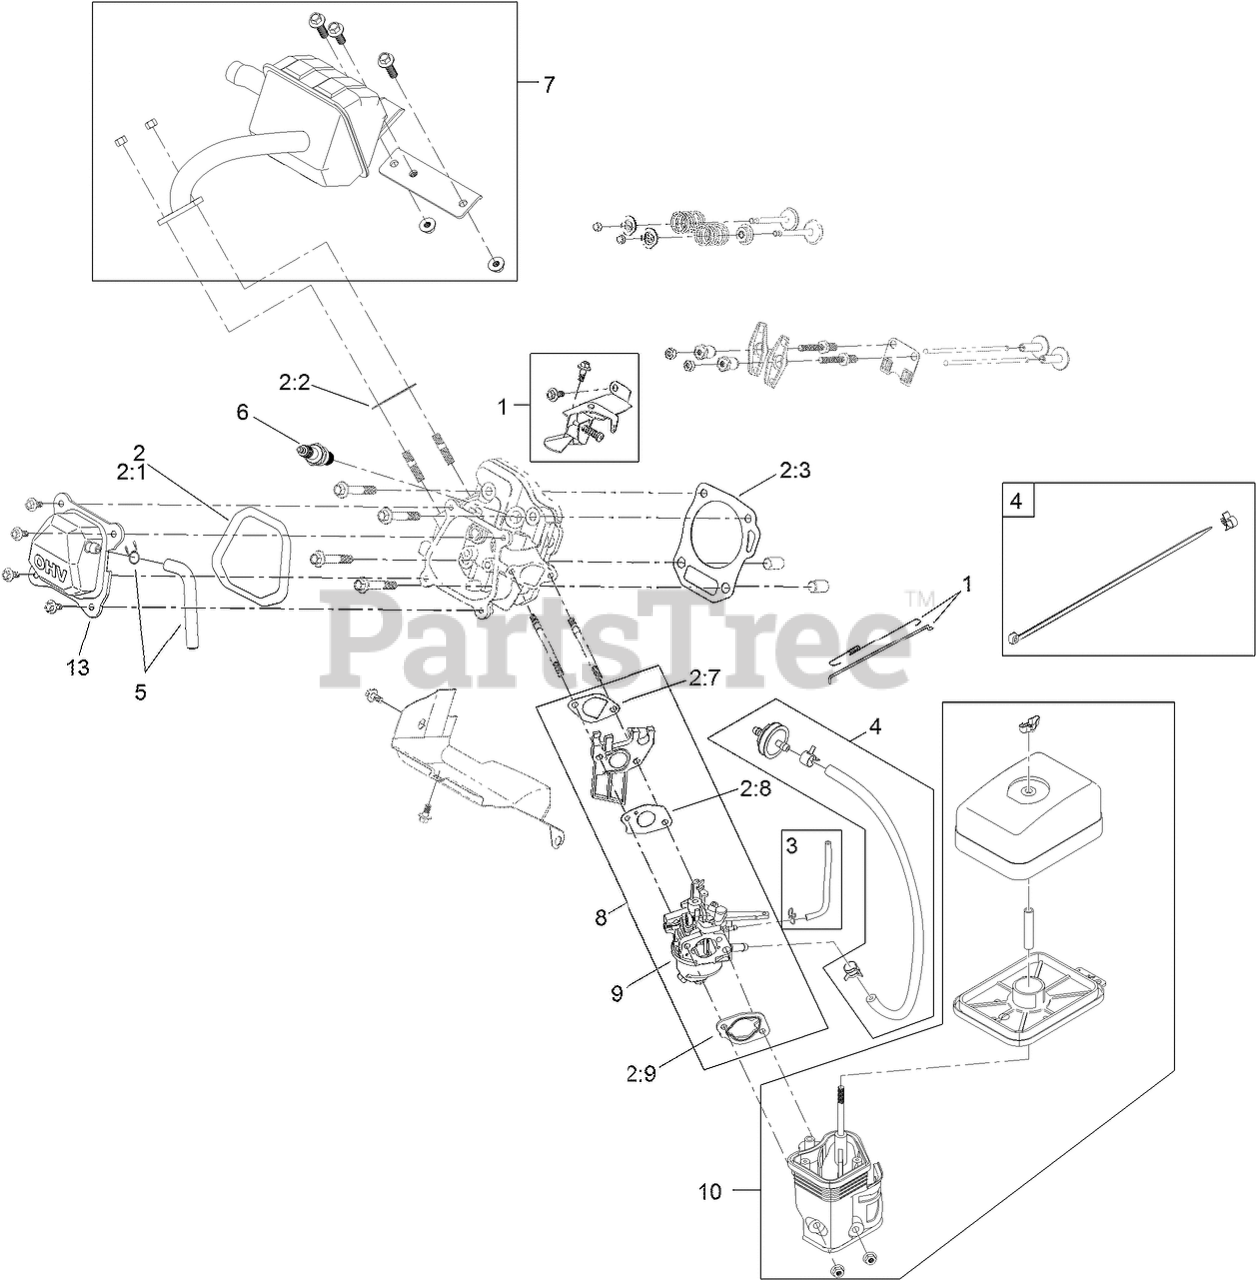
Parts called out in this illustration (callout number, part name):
1	GOVERNOR KIT
2	GASKET AND SEAL KIT
2:1	GASKET-COVER, VALVE
2:2	Gasket-Exhaust
2:3	GASKET-HEAD, CYLINDER
2:4	Seal-Oil
2:6	GASKET-COVER, CRANKCASE
2:7	GASKET-CARBURETOR
2:8	GASKET-CARBURETOR
2:9	GASKET-CARBURETOR
3	PRIMER LINE KIT
4	FUEL LINE KIT
5	BREATHER TUBE KIT
6	PLUG-SPARK
7	MUFFLER KIT
8	CARBURETOR KIT
9	CARB REPAIR KIT WITH GASKETS
10	HEATER BOX KIT
13	VALVE COVER ASM
